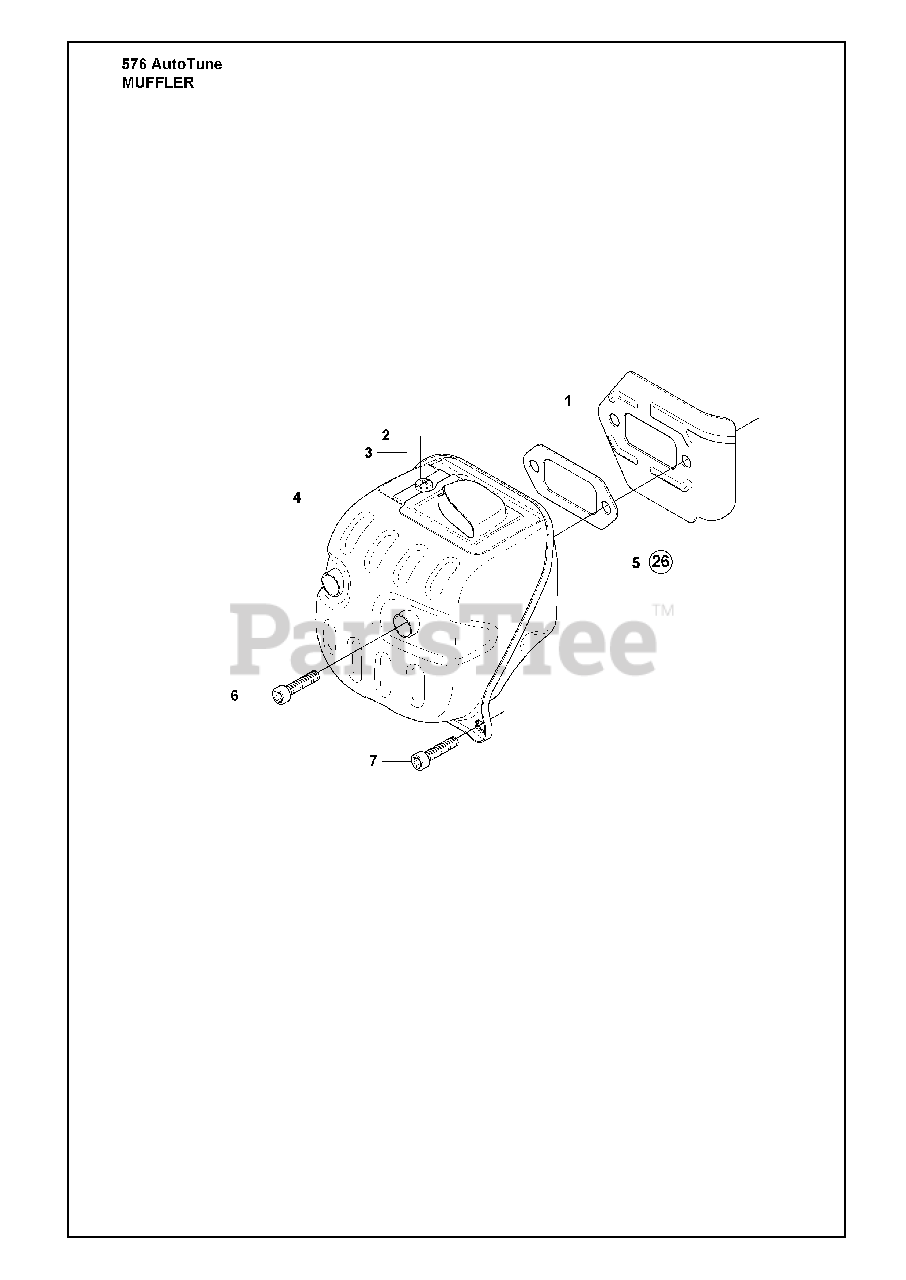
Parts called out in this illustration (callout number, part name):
4	MUFFLER ASSY (FF CE)
4	MUFFLER ASSY (DF US)
6	SCREW MC6S 6X20
26	GASKET KIT
